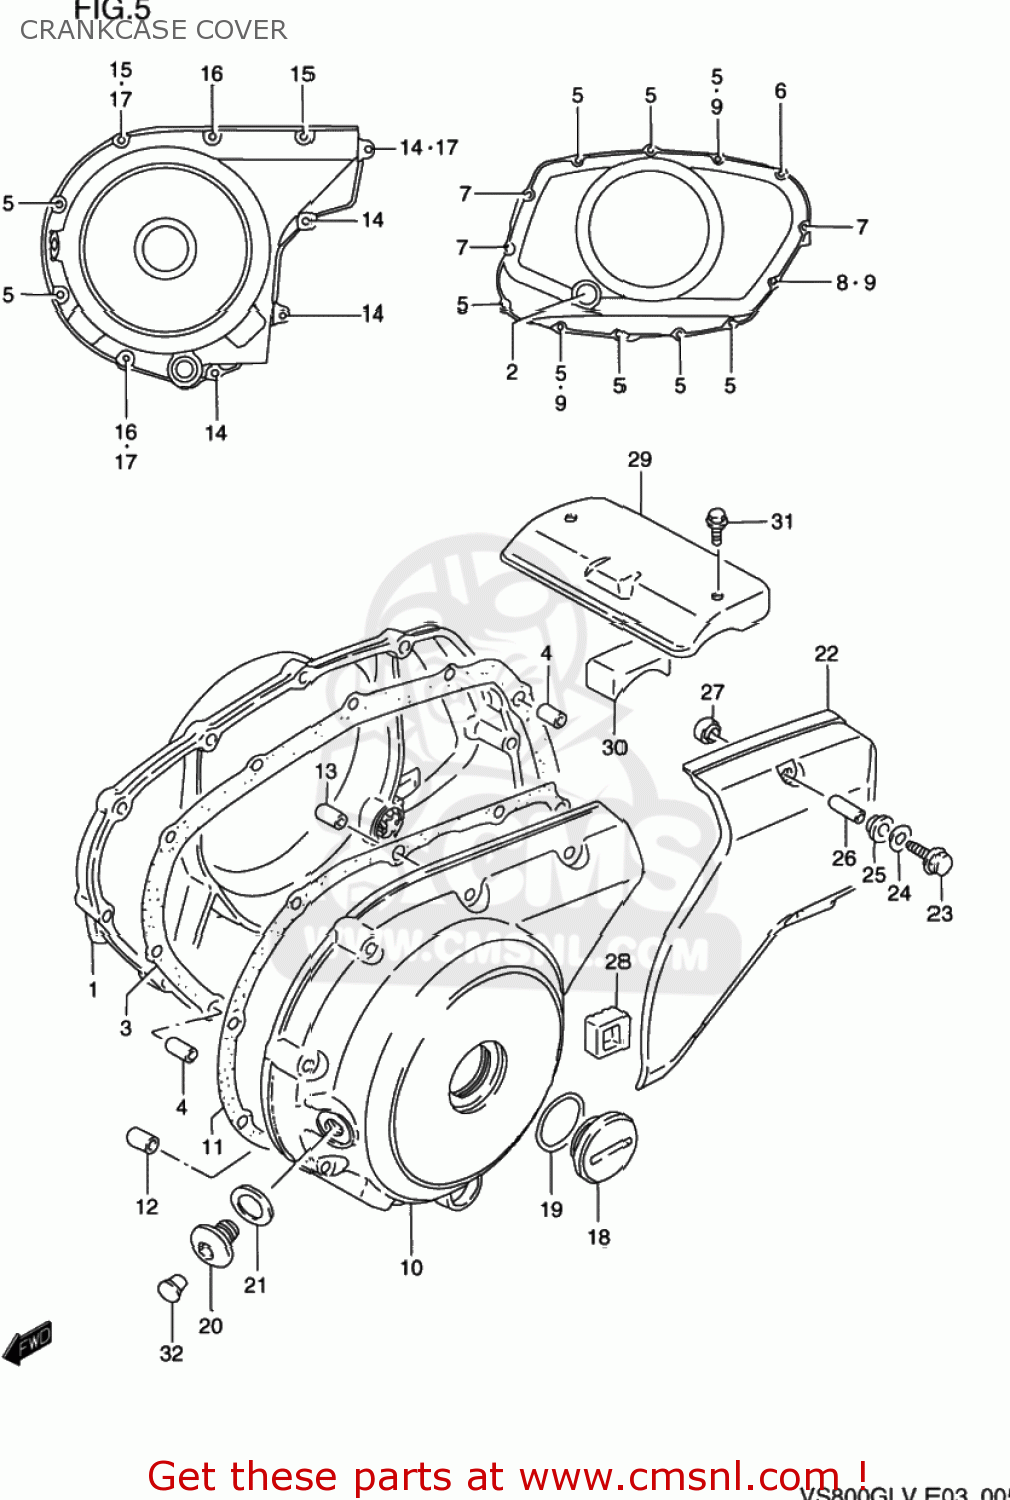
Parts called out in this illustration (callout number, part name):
1	COVER,CLUTCH
2	LENS,OIL LEVEL CHECK
3	GASKET,CLUTCH COVER (NAS)
4	PIN
5	BOLT
6	BOLT
7	BOLT
8	BOLT
9	GASKET(5.8X13X1.2) (NAS)
10	COVER,GENERATOR
11	GASKET,GENERATOR COVER (NAS)
12	PIN(8.4X11X20)
13	PIN
14	BOLT
15	BOLT
16	BOLT
17	GASKET(5.8X13X1.2) (NAS)
18	Chrome Crankshaft Plug
19	O RING(D:3.1,ID:32.7)
20	PLUG,14X12
21	GASKET(14X19.2X2) (NAS)
22	COVER,SECONDARY GEAR CASE
23	BOLT
24	WASHER
25	WASHER(8.7X15X2.1)
26	SPACER
27	WASHER(8.7X16X5)
28	DAMPER,SECONDARY COVER
29	COVER,STARTER MOTOR
30	DAMPER,MOTOR COVER
31	BOLT
32	CAP(OD:12)
